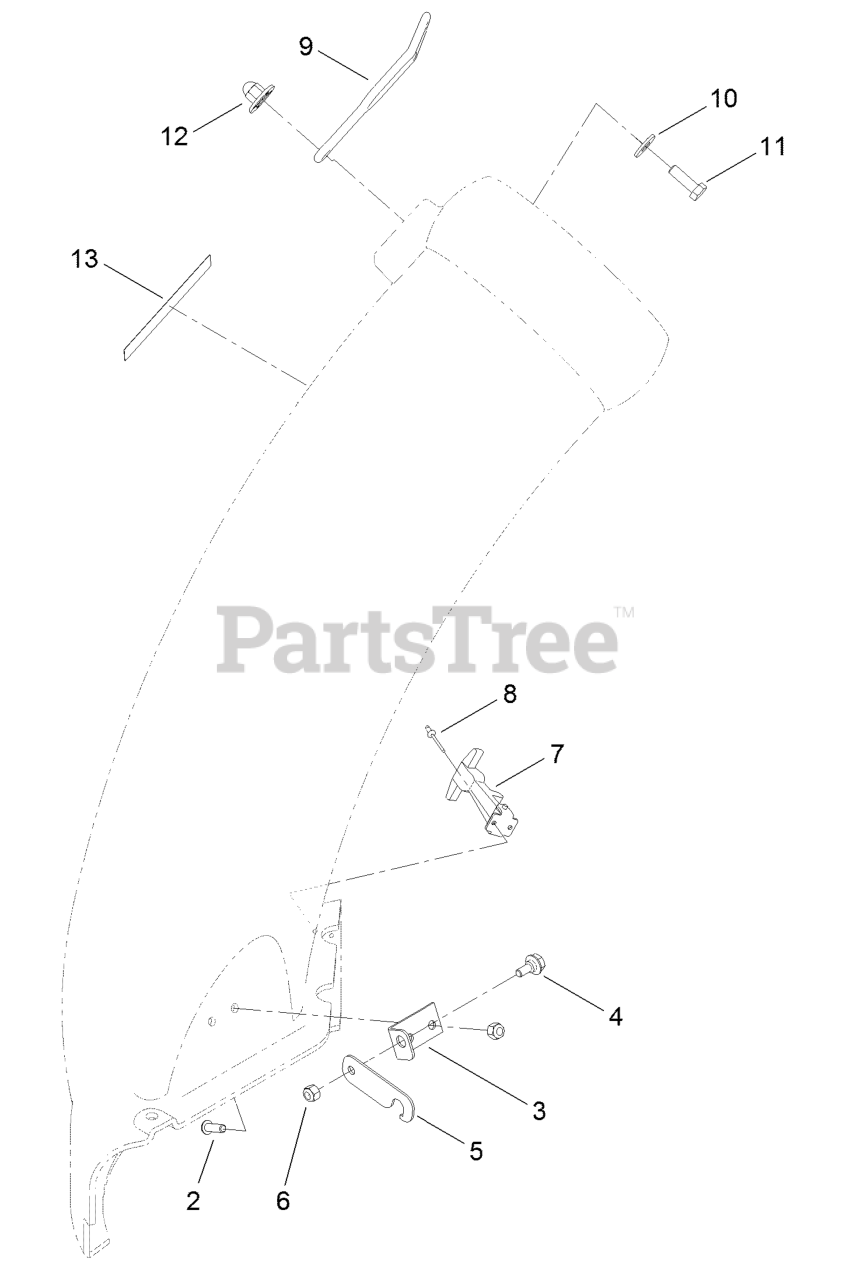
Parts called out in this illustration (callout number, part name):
2	SCREW-HSBH
3	PLATE-PIVOT
4	SCREW-SHOULDER,HWH
6	NUT-LOCK, NI
7	HANDLE ASM
8	RIVET-POP
9	RETAINER-DUCT
10	WASHER-FLAT
11	SCREW-HH
12	NUT-IMPELLER
13	DECAL-DANGER
